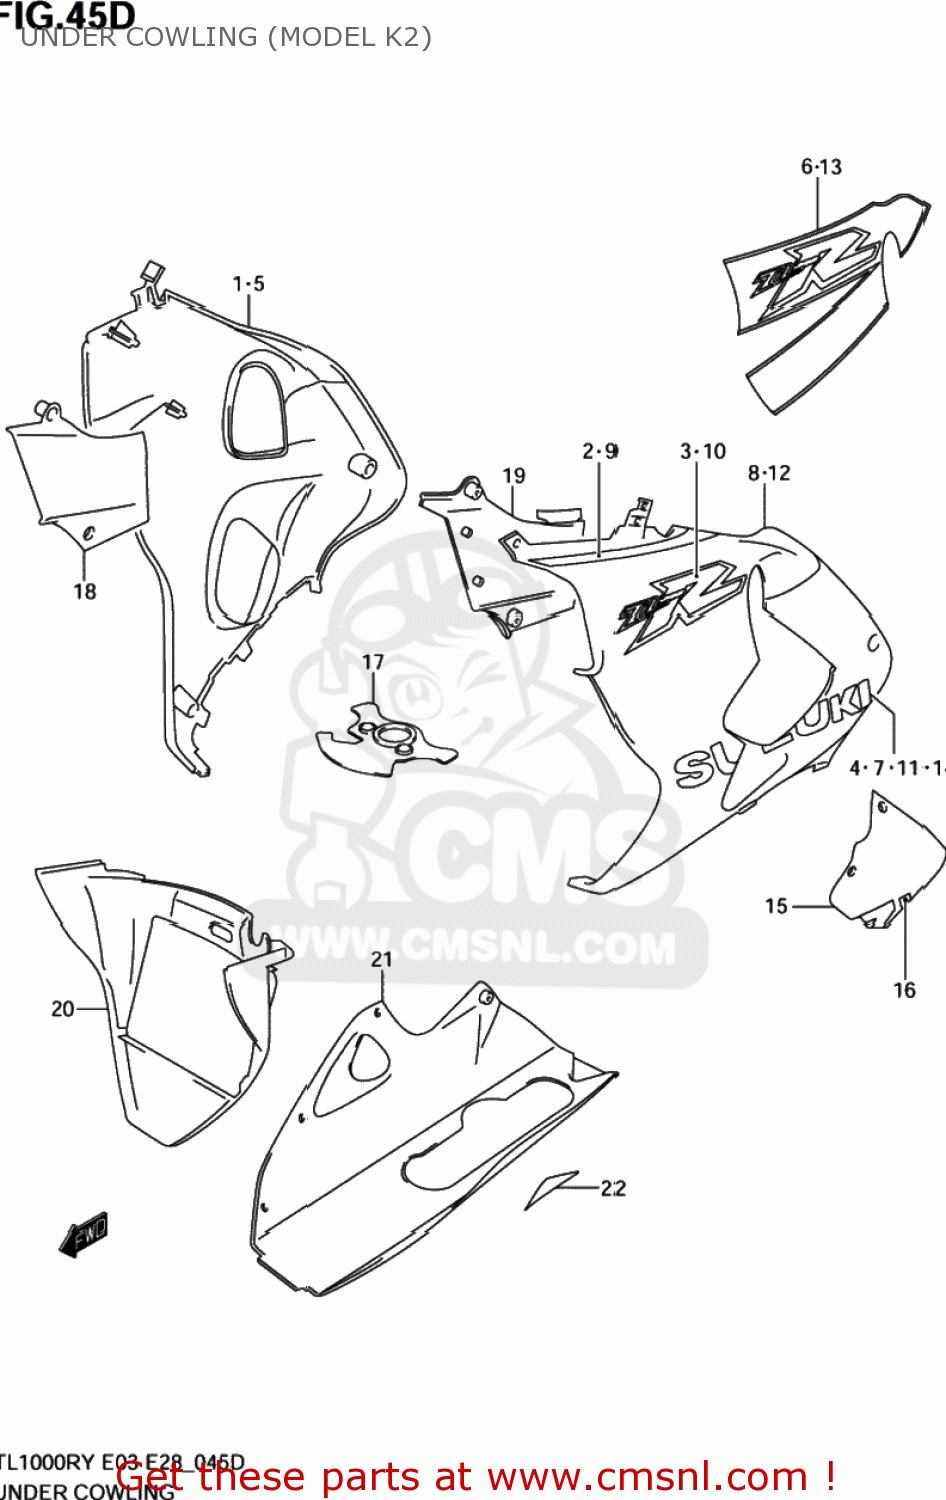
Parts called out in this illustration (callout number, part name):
1	COWLING ASSY,UNDER,R
2	TAPE,COWL UNDER UPR,R
3	EMBLEM,TL1000R,R
4	EMBLEM,UNDER,SUZUKI,R
5	COWLING ASSY,UNDER,R
6	TAPE,UNDER UPR,R
7	EMBLEM,UNDER,SUZUKI,R
8	COWLING ASSY,UNDER,L
9	TAPE,COWL UPR,L
10	EMBLEM,TL100R,L
11	EMBLEM,UNDER,SUZUKI,L
12	COWLING ASSY,UNDER,L
13	TAPE,UNDER UPR,L
14	EMBLEM,UNDER,SUZUKI,L
15	LID ASSY,COWL UNDER,L
16	TAPE,COWL LID,L(WHITE)
17	COVER,LWR BRACKET
18	COWLING,UNDER INNER,R
19	COWLING,UNDER INNER,L
20	COWLING,UNDER CTR
21	COWLING ASSY,UNDER RR
22	TAPE SET,UNDER RR
